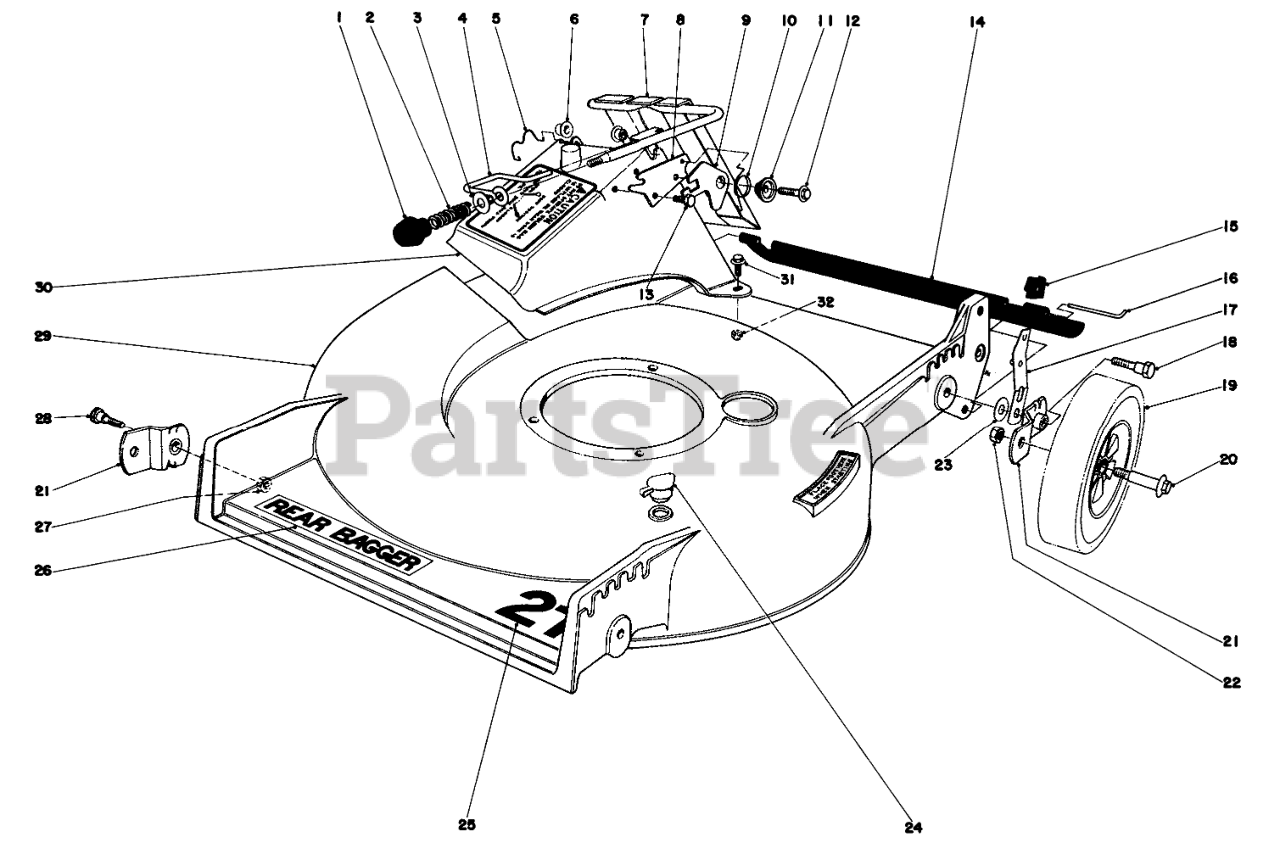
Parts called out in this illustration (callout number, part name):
2	COMPRESSION SPRING
3	WASHER
4	DOOR LATCH
5	Door Retainer
6	BUSHING-NYLON
7	DOOR & HANDLE WA
8	DOOR LATCH PLATE
9	Latch Safety
10	TORSION SPRING
11	Latch Spacer
12	Screw
13	SCREW-HWH
14	SHIELD - TRAILING
15	KNOB-ARM
16	Rod Shield
17	SPRING ARM ASM (R&S)
18	5/16-18 PIVOT SCREW
19	WHEEL & TIRE ASM
20	BOLT-WHEEL
21	PIVOT ARM ASM A
22	Nut
23	WASHER-PIVOT
24	WASHOUT PLUG
25	Decal 21"
26	DECK DECAL
27	Nut
28	PIVOT SCREW
29	Deck
30	DISCHARGE CHUTE B
31	SCREW-HH
32	NUT-LOCK, NI
